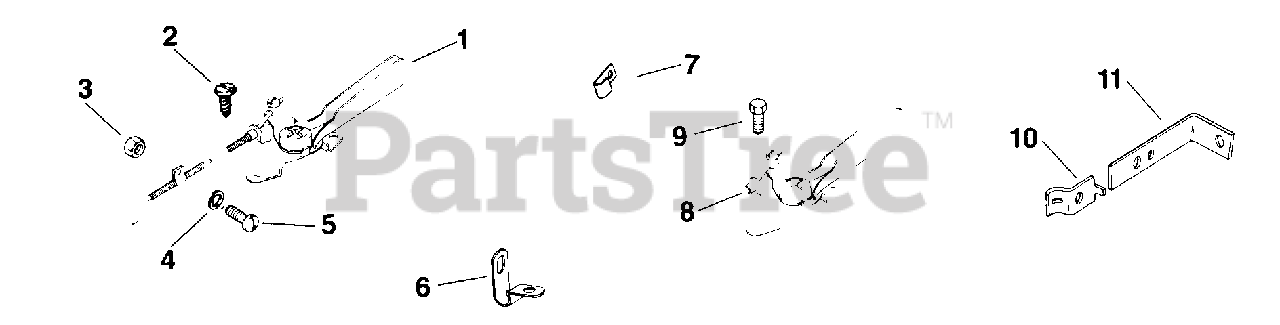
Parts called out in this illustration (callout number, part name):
2	SCREW, WSH HD TAP #8-18X1/2" USE 25 086 91-S
4	WASHER, SPRING LOCK #8
5	SCREW, SLT FLS 8-32X3/8" USE 25 086 68-S
